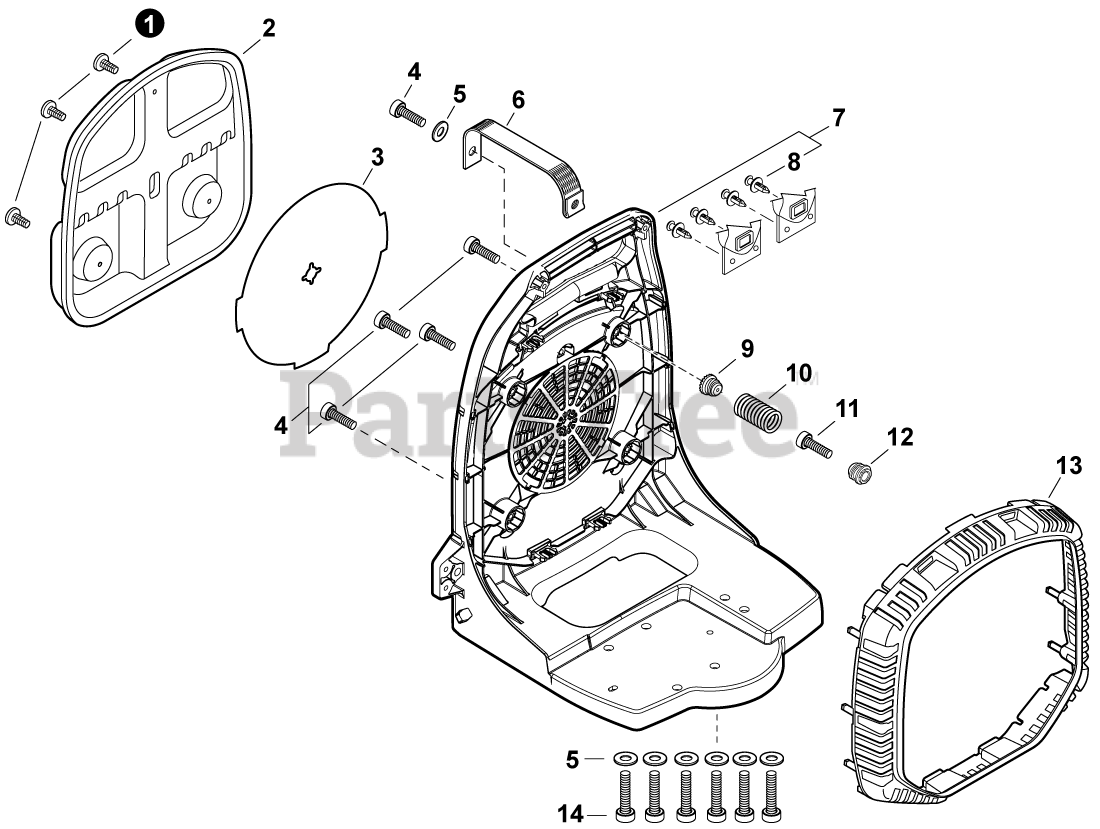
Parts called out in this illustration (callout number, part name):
2	CUSHION, BACKPACK
3	INSERT, COLD WEATHER
4	BOLT, TORX 5x20
5	WASHER 5.5x16x2T
6	STRAP, SAFETY 1.2x100
7	FRAME, BACKPACK WITH CLIPS
9	HOLDER, SPRING
10	SPRING, COMPRESSION
11	BOLT, TORX 5x16
12	HOLDER, SPRING
13	GUARD, DEBRIS
14	SCREW 5x25
